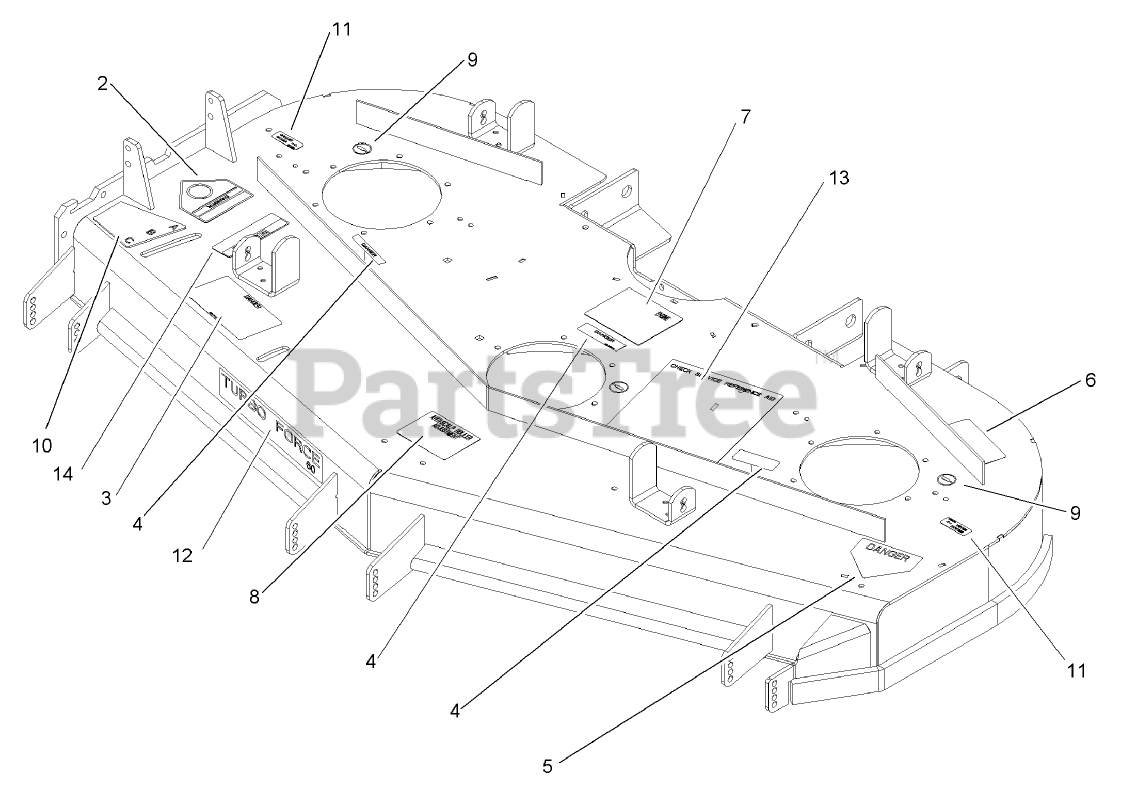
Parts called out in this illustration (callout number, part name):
2	DECAL-DANGER
3	DECAL-DANGER, THROWN OBJECT
4	DECAL-COVER, MISSING
5	DECAL-DANGER
6	DECAL-TORQUE
7	Decal-Routing, Belt
8	DECAL-SCALP, ANTI
9	DECAL-GREASE
10	DECAL-ADJUSTMENT, BAFFLE
11	Decal-Grease
13	Decal-Service, Check
14	DECAL-WARNING
